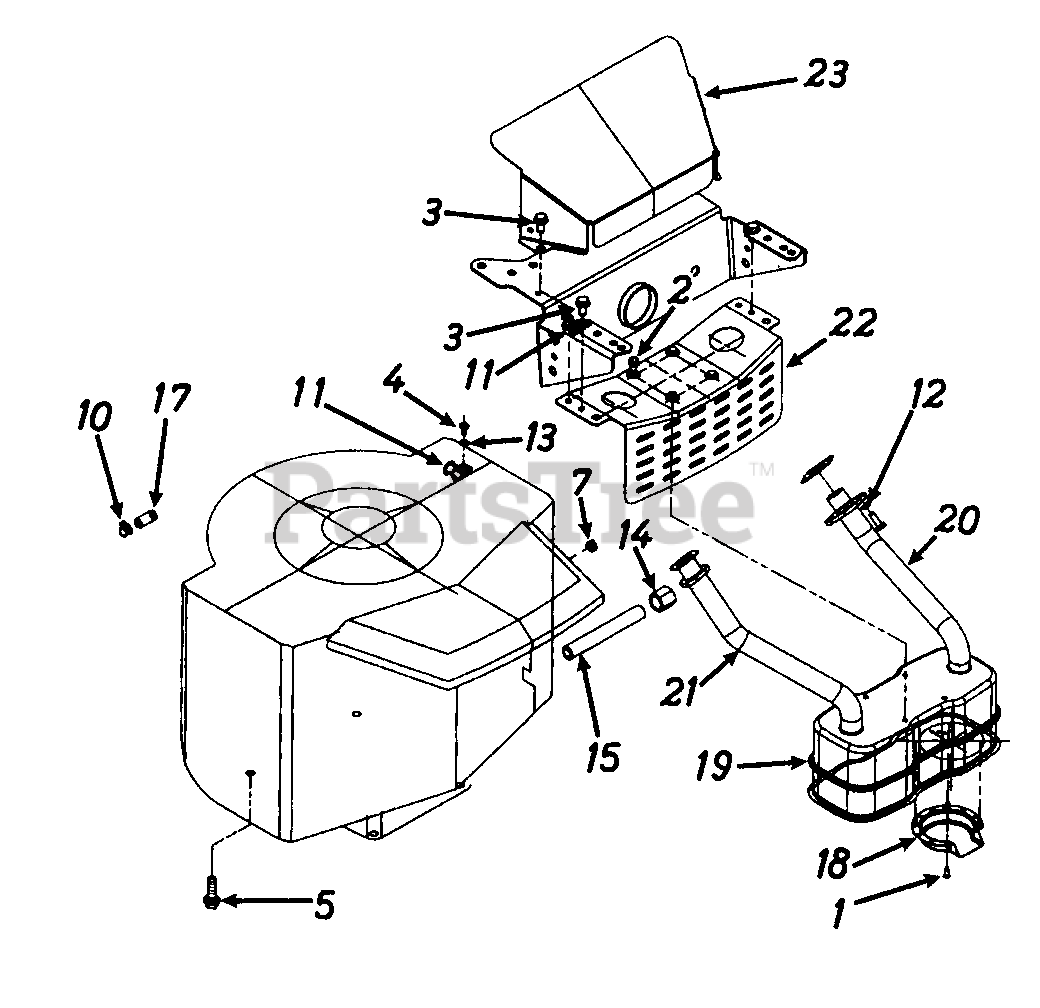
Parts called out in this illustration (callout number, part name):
1	Hex Tap Scr. #8-32 x .38" Lg.
2	Hex Wash TT-Tap Scr 1/4-20 x .5" Lg.
3	Hex Wash TT-Tap Scr 5/16-18 x .62" Lg
4	Truss Mach Scr. #10 x .5" Lg.
5	Hex Hd Tap Scr 3/8-16 x 1.25" Lg.
7	Hex Sems Nut 1/4-20 Thd
10	Hose Clamp
11	Clamp
12	L-Wash 1/4" I.D.
13	Fl-Wash. .188" I.D. x .438" O.D.
14	Oil Drain Cap
15	Pipe Nipple 3/8 x 18 NPT.
17	Fuel Line 26" Lg
18	Deflector: Muffler
19	Muffler
20	Exhaust Pipe - L.H.
21	Exhaust Pipe - R.H.
22	Muffler Bracket
